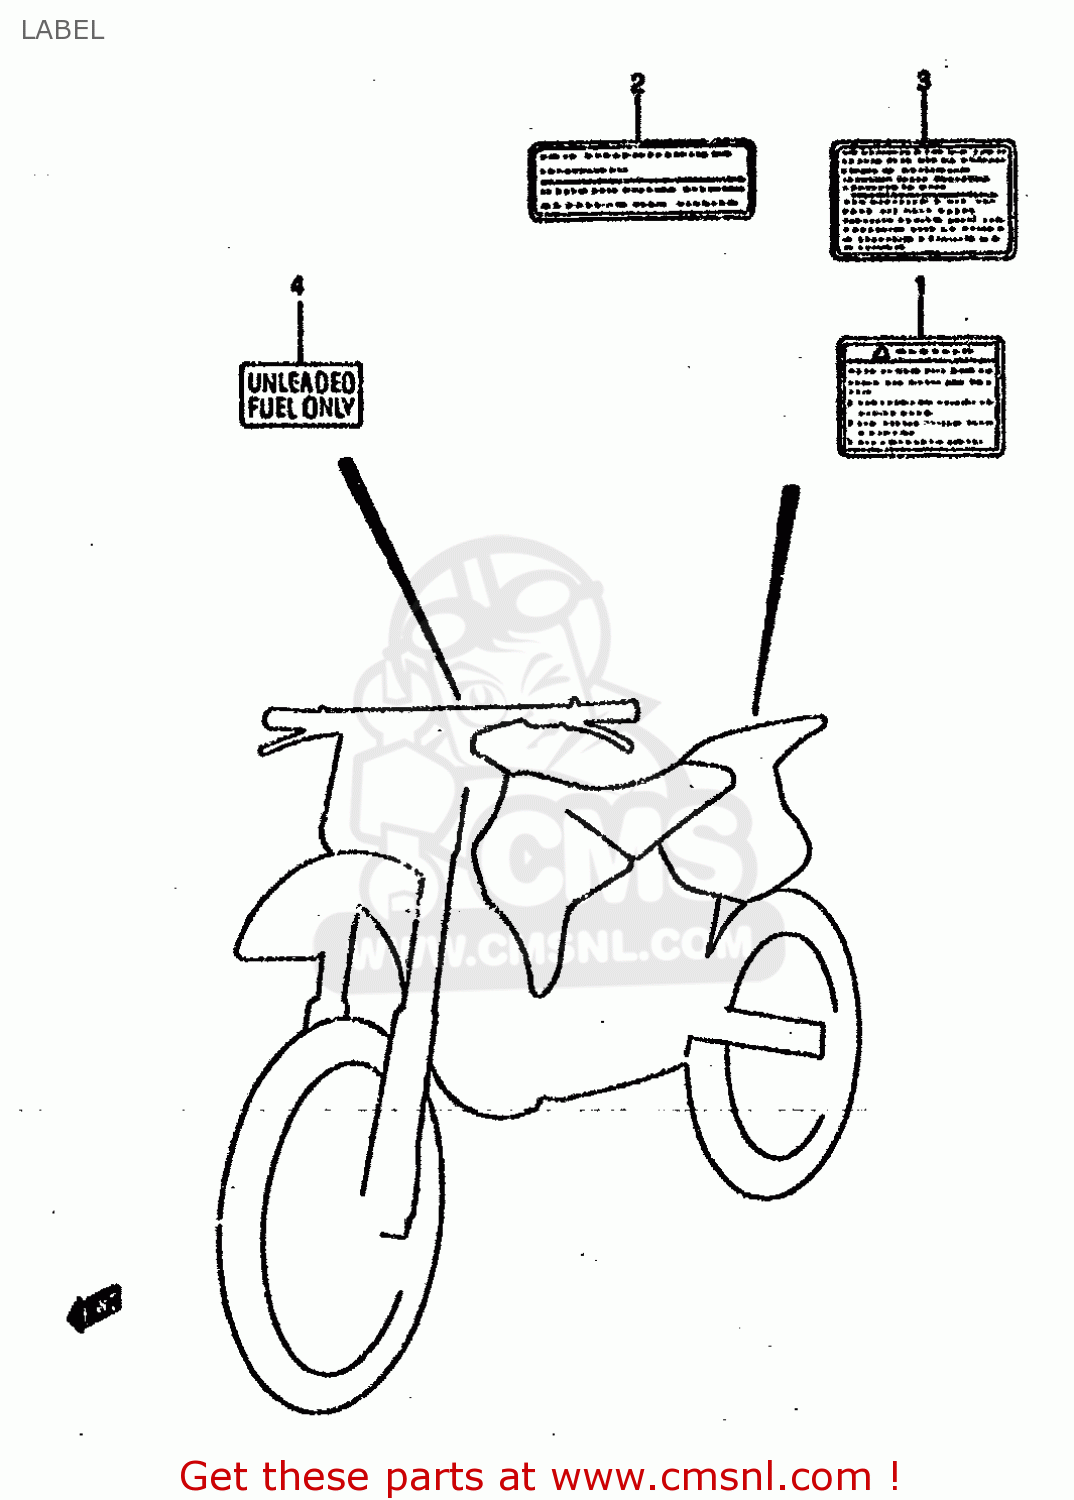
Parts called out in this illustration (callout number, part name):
1	LABEL
2	LABEL,WARNING NO.2
3	LABEL,WARNING
4	LABEL,UNLEADED FUEL
5	MANUAL,OWNER'S
